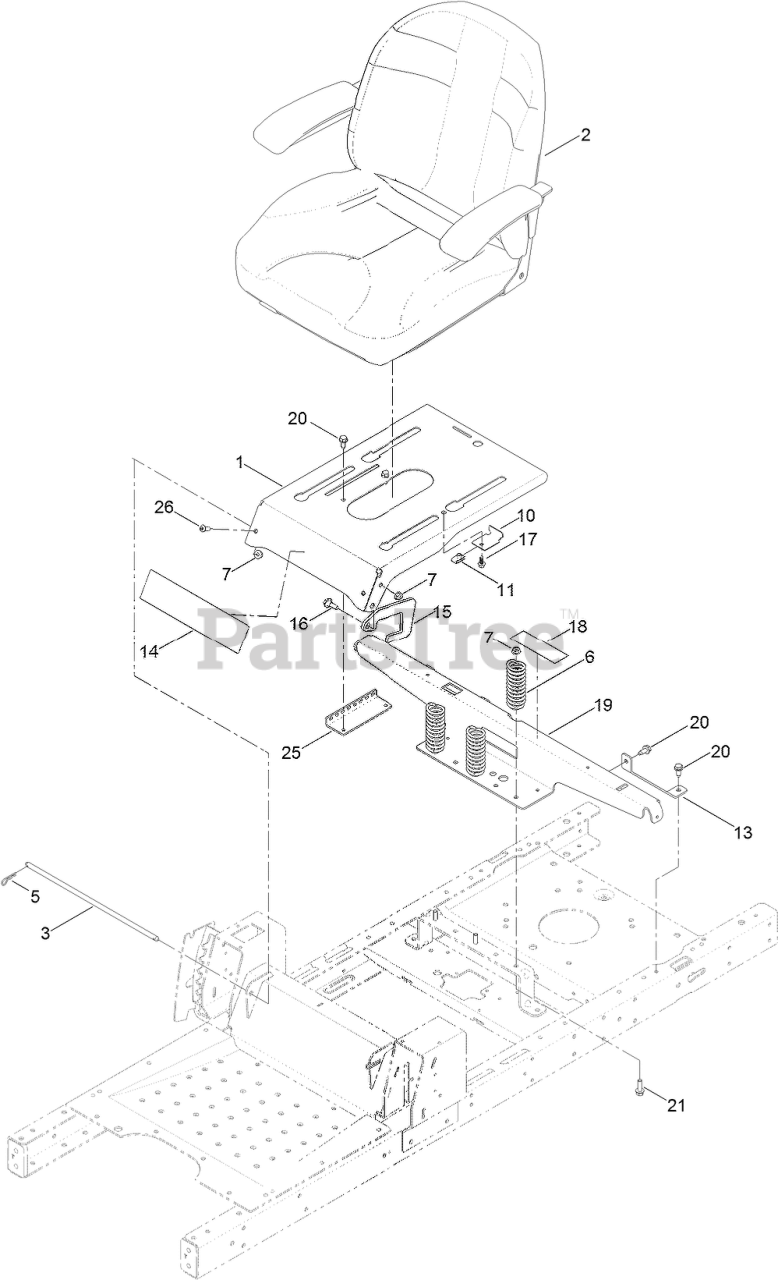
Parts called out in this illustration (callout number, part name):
1	PAN-SEAT
2	SEAT ASM
3	ROD-PIVOT, NARROW
5	PIN-COTTER
6	SPRING-COMPRESSION
7	NUT-HF, NI
10	BRACKET-STOP, SEAT
13	SUPPORT-TANK, REAR
14	DECAL-TIMECUTTER
15	PLATE-STOP
16	SCREW-SHOULDER
17	SCREW-HHF
18	DECAL-SERVICE, CE
19	SUPPORT-POD
20	SCREW-HWHTF
21	SCREW-HHF
25	BRACKET-LATCH, SEAT
26	SCREW-HSBH
